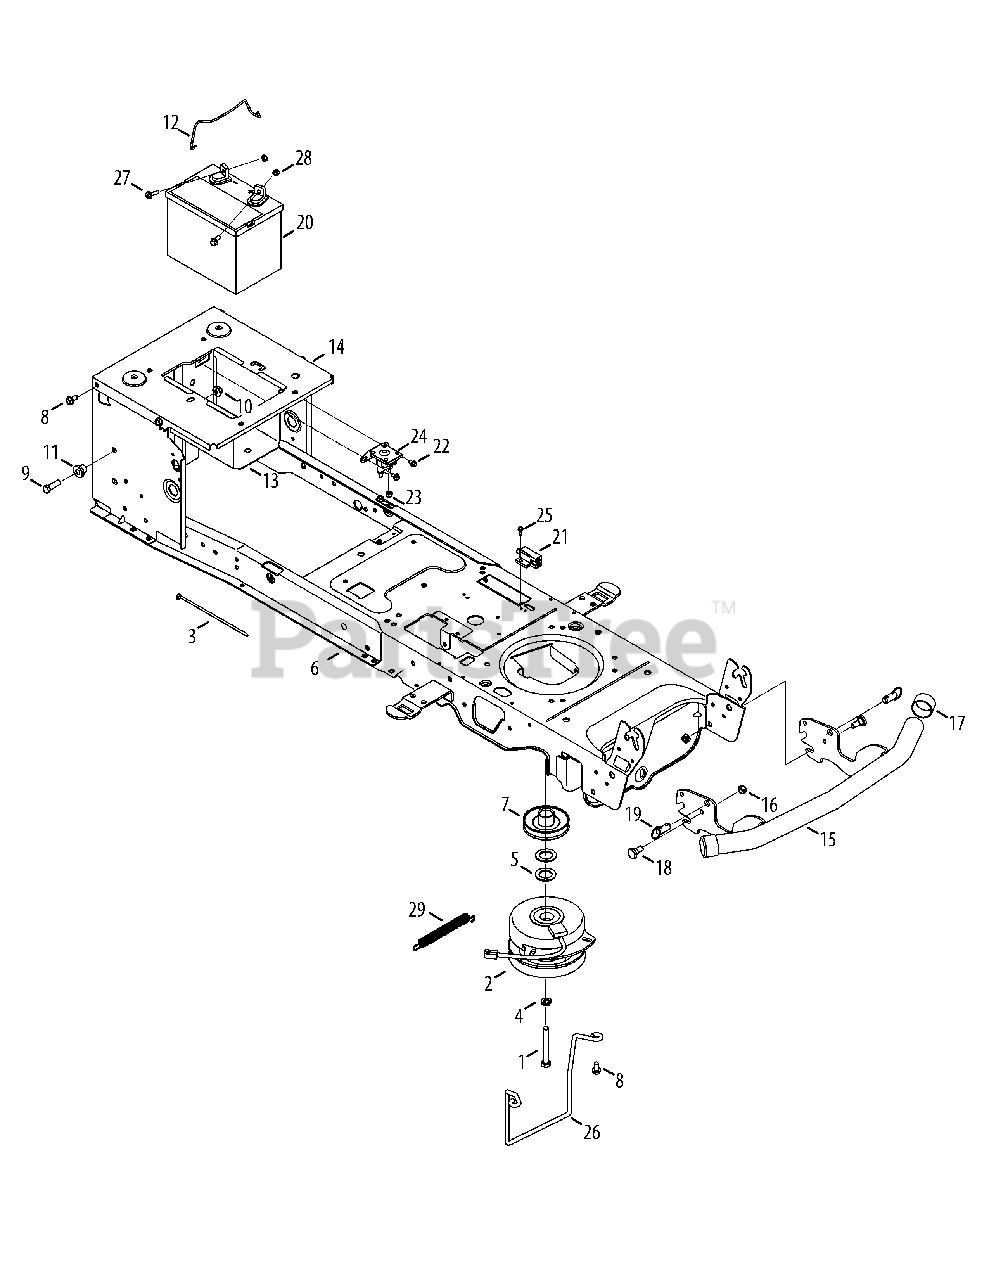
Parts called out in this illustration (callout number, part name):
1	Hex Head Screw, 7/16-20x3.50
2	Electric PTO Clutch
3	Cable Tie, 3/16 x .05 x 7.4
4	Lock Washer, 7/16
5	Flat Washer, 1.031 x 1.620 x .095
6	Frame
7	Electric PTO Engine Pulley
8	Taptite Screw, 5/16-18x.750
9	Hex Head Screw, 3/8-16x1.25
10	Flangelock Nut, 3/8-16
11	Shoulder Spacer, .38 x 1.0 x .70
12	Battery Holder Rod
13	Battery Tray
14	Seat Frame Bracket
16	Hexlock Nut, 3/8-16
17	Bumper Cap
18	Shoulder Bolt, .496 x .336
19	Quick Release Pin
20	Battery
21	Interlock Switch
22	Taptite Screw, 1/4-20x0.375
23	Flangelock Nut, 1/4-20
24	Solenoid, 12 V
25	Shoulder Screw, #10-32x.500
26	Belt Keeper Rod
27	Hex Head Flange, 1/4-20x.75
28	Sems Nut, 1/4-20
29	Spring, Extn, .56 Dia X 5.52
